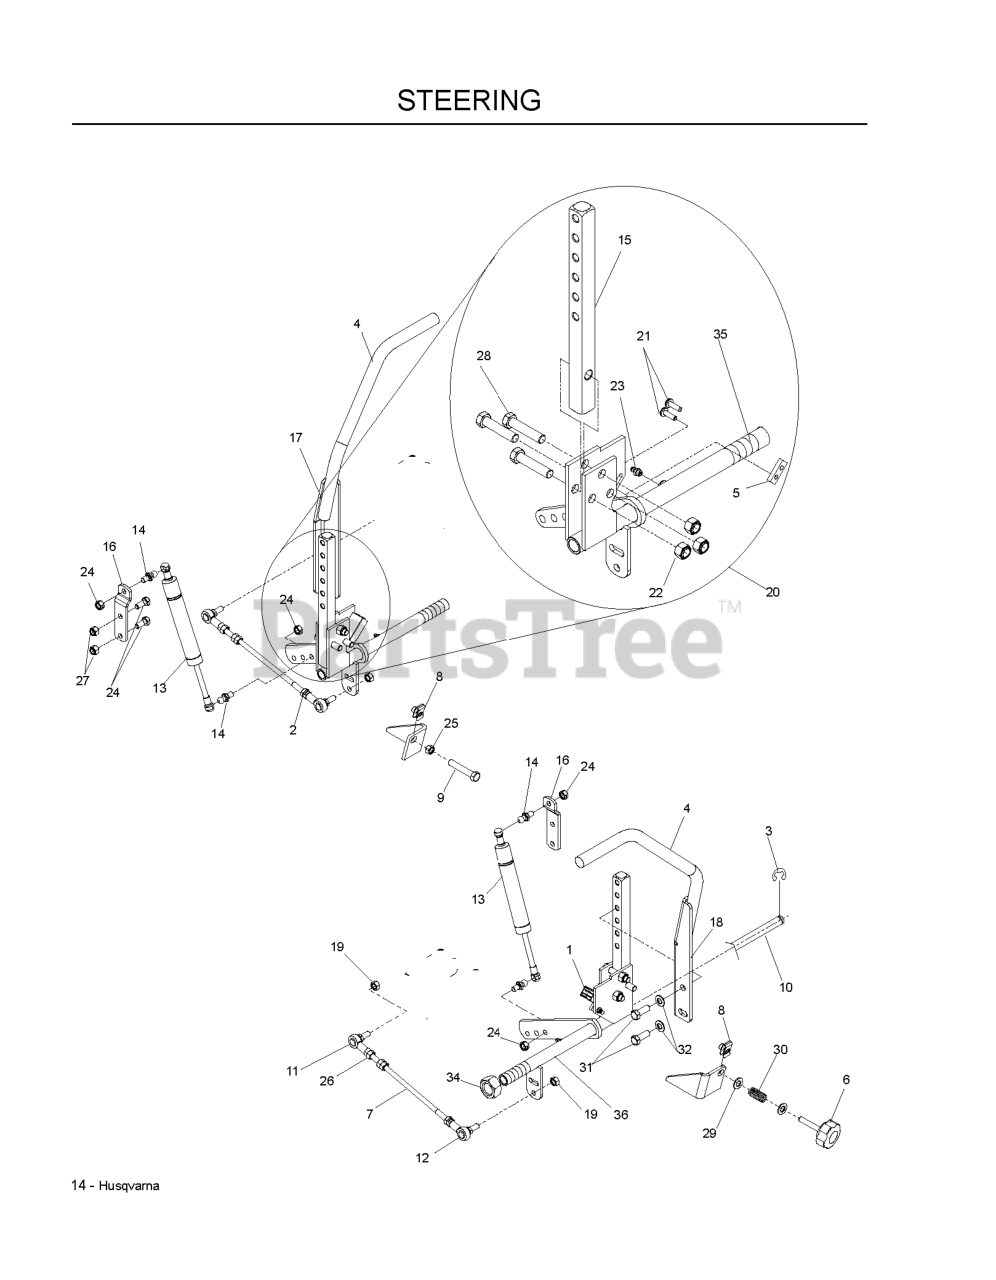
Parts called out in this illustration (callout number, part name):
1	SWITCH, INTERLOCK
2	NUT 5/16F LEFTHAND
3	E-RING 1/2 (2 2)
4	GRIP - DRIVE LEVER 12"
5	TAPPED PLATE
6	ADJUSTMENT KNOB
7	PUMP CONTROL LINK
8	U-CLIP 5/16-18 NUT RETAINER
9	HCS 5/16-18X1-3/4 TPBLT
10	CONTROL SHAFT
11	SPHERICAL ROD END, RH
12	SPHERICAL ROD END, LH
13	DAMPENER W/EXT SEAL
14	STUD.BALL.10MM
15	CONTROL ARM
16	DAMPENER ARM
17	ASSEMBLY, DRIVE LEVER RT
18	ASSEMBLY, DRIVE LEVER LT
19	NUT 5/16F NYLOC
20	CONTROL ASM - ADJ, LT
20	CONTROL ASM - ADJ, RT
21	SCREW #10-24 X 5/8
22	NUT 3/8-16 NYLOC
23	ZERK
24	NUT 5/16C CENTERLOCK
25	NUT 5/16C HEX
27	NUT 5/16 NYLOC
28	HCS 3/8-16 X 1 3/4 GR5
29	WASHER 5/16 FLAT
30	COMPRESSION SPRING
31	HCS 3/8-16X1.GRD.5.ZD
32	WASHER, 3/8 DISC SPRING SPEC
33	HCS 5/16C X 3/4
34	NUT 3/4 X 16 HEX CTR
35	CONTROL-DRIVE RT
36	DRIVE CONTROL, LT
